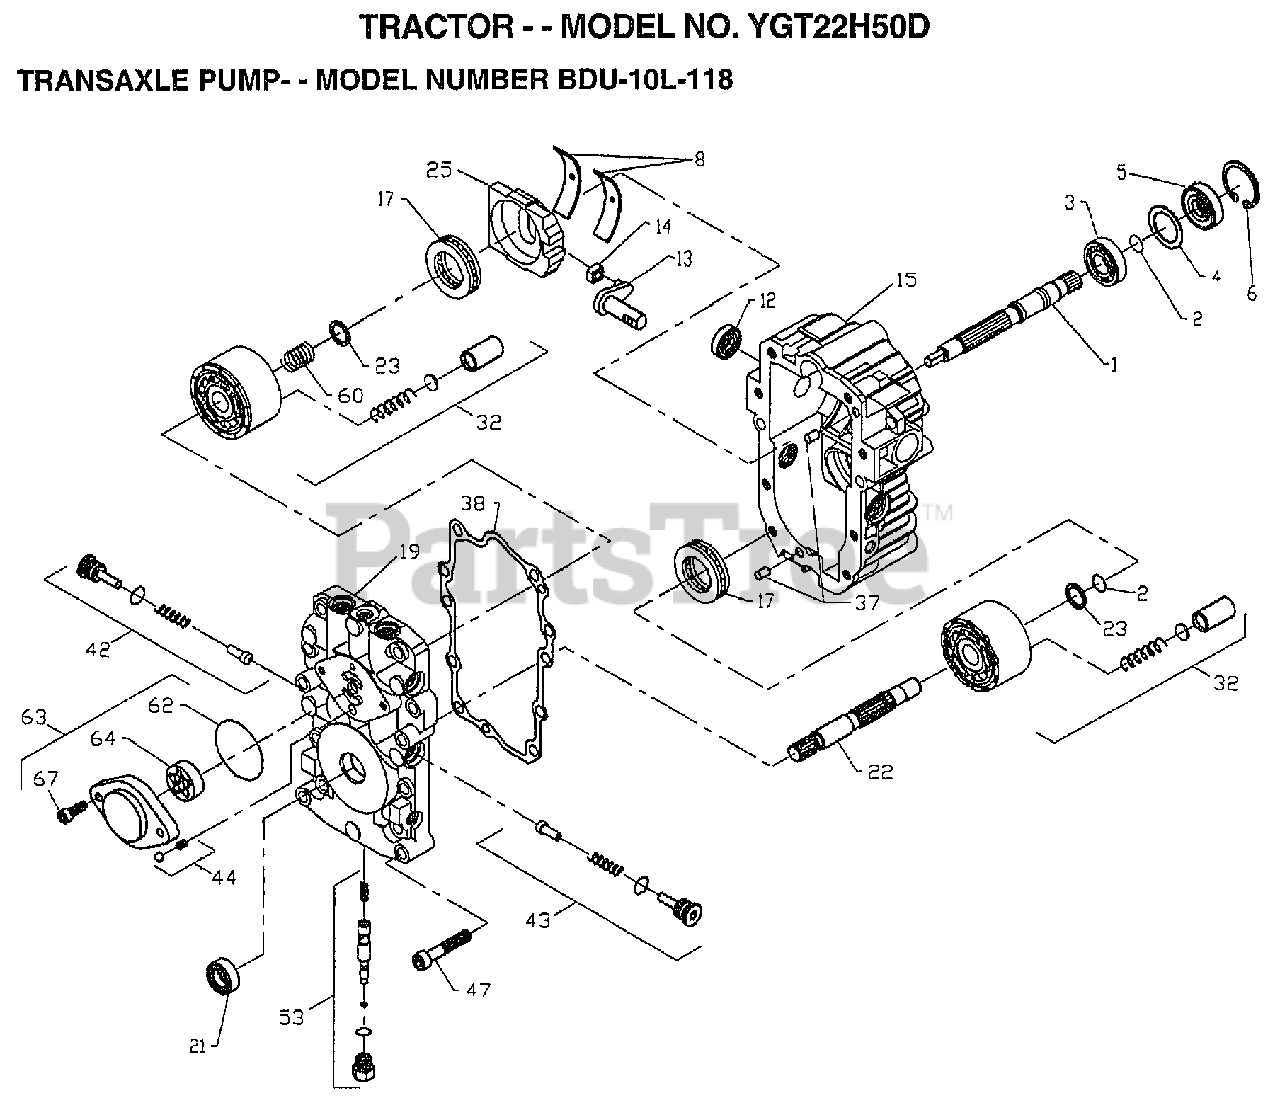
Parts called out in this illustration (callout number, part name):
1	SHAFT.PUMP.50158
2	RETAINIANG RING-(2003016)
3	BALL BEARING
4	SPACER
5	SEAL LIP
6	RING.RET.2003052
8	CRADLE BEARING (2003023)
12	SEAL.9008000-0126
13	TRUNION ARM (2003005)
14	GUIDE.2000015.HYD
15	KIT.HSG.2513035.
19	KIT.CENTER.50642
21	LIP SEAL-9008000-0127
22	SHAFT.MOT.2003034
23	WASHER.2003017
25	"SWASHPLATE,VARIAB"
32	BLOCK.CLYN.70079.
37	PIN
38	GASKET.20030600
42	KIT.VALVE.2510050
43	KIT.VALVE.2510050
44	KIT.RELI.2510011.
47	SCREW9007314-0808
53	"KIT,BYPASS VALVE"
60	SPRING.2003014.
62	0RING.90041011340
63	KIT.CHARG.2513027
64	GEROTOR.J1041008
67	SCREW.CAP.50095.
